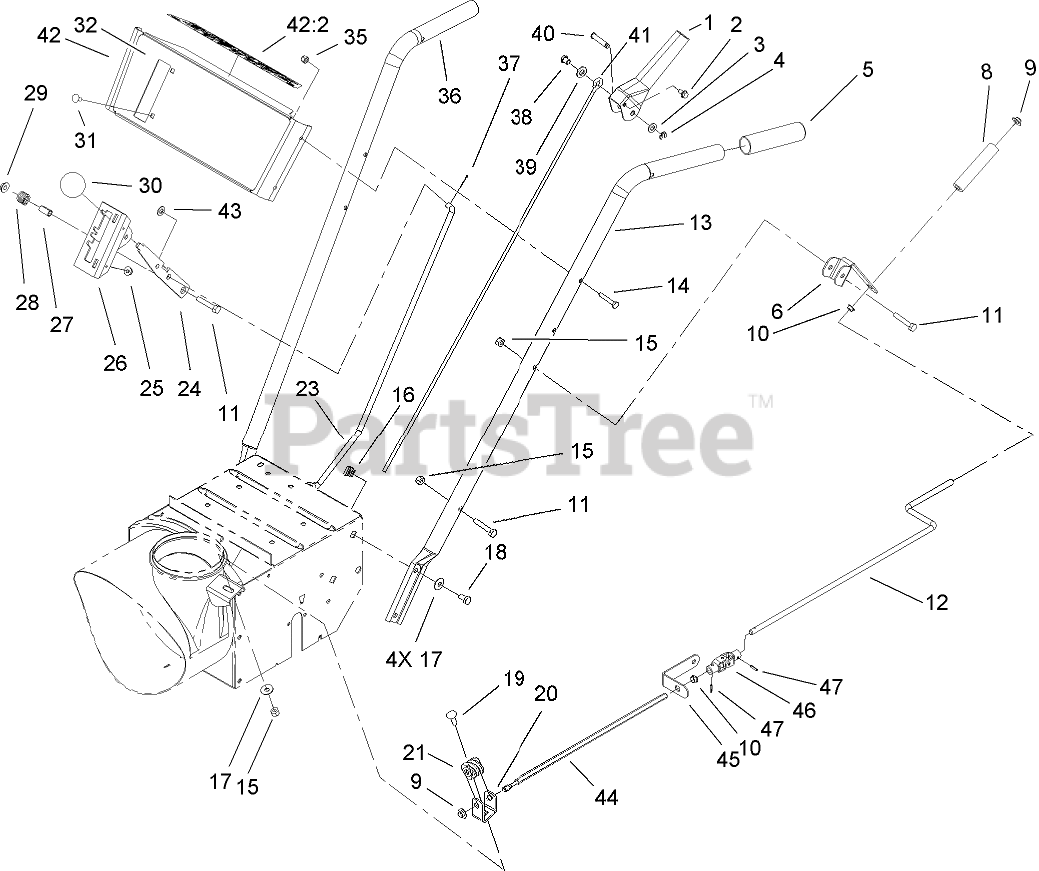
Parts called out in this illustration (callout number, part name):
1	HANDLE-CONTROL
2	SCREW-HHF
3	WASHER-PLAIN
4	RING-CLIP
5	GRIP-HANDLE
6	BRACKET-ROD, UPPER CHUTE
8	GRIP-CONTROL, CHUTE
9	RETAINER-PUSH ON
10	Bushing
11	SCREW-HH
12	ROD-CHUTE, UPPER
13	HANDLE-LEFT
14	SCREW-HH
15	NUT-LOCK, NI
17	WASHER-BELLEVILLE
18	SCREW-HH
19	SCREW-CARR
20	BRACKET-WORM
21	GEAR-WORM, CHUTE
23	ROD-SELECTOR, SPEED
24	Selector-Speed
25	NUT-HF
26	MOUNT-SELECTOR, SPEED
27	SPACER
28	SPRING
29	NUT-HF
31	SCREW-CARR
32	DECAL-ESCUTCHEON
35	NUT-LOCK, NI
36	HANDLE-RIGHT
37	PIN-COTTER
38	POST-MOUNTING, LINKAGE
39	WASHER-FLAT
40	PIN-LEVER, CONTROL
41	LINK-UPPER
42	ESCUTCHEON PANEL ASM
42:2	DECAL-ESCUTCHEON, BACK
43	WASHER-PLAIN
44	ROD-CHUTE, LOWER
45	BRACKET-ROD, LOWER
46	JOINT-UNIVERSAL
47	PIN-ROLL
